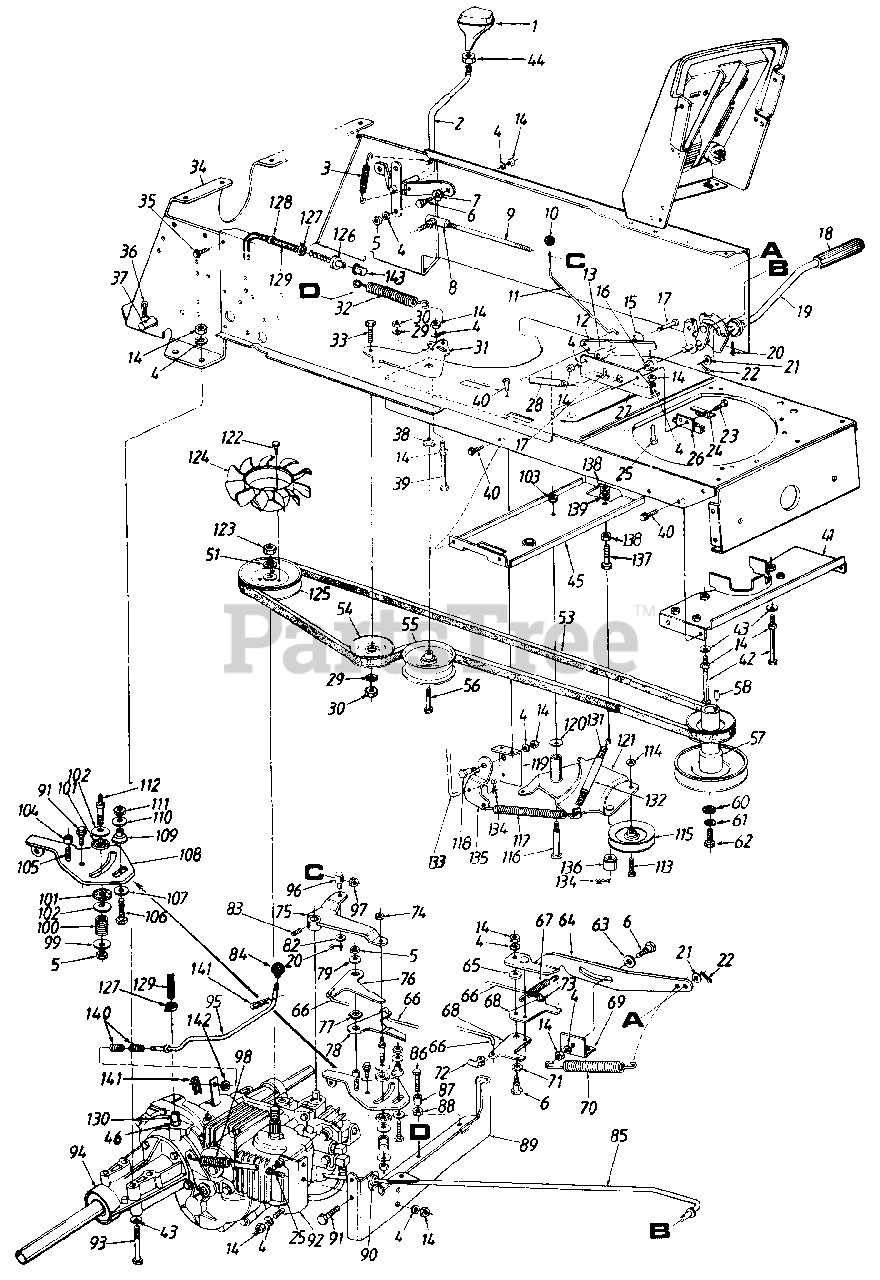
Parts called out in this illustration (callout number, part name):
1	Shift Knob
2	Speed Control Lever Ass'y.
3	Ext. Spring 2.75" Lg.
4	L-Wash. 5/16" I.D.
5	Hex Nut 5/16-24 Thd.
6	Shld. Bolt .437" Dia. x .268"
7	Spr. Wash. .445" I.D. x .75" O.D.
8	Ball Joint 5/16-24 Thd.
9	Speed Selector Adjusting Rod
10	Ball Knob
11	Brake Lockout Rod
14	Hex Nut 5/16-18 Thd.
15	Shld. Spacer .27" Lg.
16	Hex Flange Bearing
17	Hex Bolt 5/16-18 x 1.25" Lg.
18	Foot Pad
21	Fl-Wash. .34" I.D. x .68" O.D.
22	Cotter Pin 1/8" Dia. x 1" Lg.
23	Hex B-Tap Scr. #10 x .62" Lg.
24	Switch Plate
25	Hex Bolt 5/16-18 x .75" Lg.
26	Safety Switch (Clutch)
27	Clutch Ass'y. Mtg. Brkt.
28	Ext. Spring 2.51" Lg.
29	L-Wash. 3/8" I.D.
30	Hex Nut 3/8-16 Thd.
31	Idler Brkt.
32	Ext. Spring 4.75" Lg.
33	Hex Bolt 3/8-16 x 1.5" Lg.
36	Hitch Pin
37	Hitch Rod
38	Shld. Spacer .625" I.D.
39	Hex Bolt 5/16-18 x 2.75" Lg.
40	Hex Wash. Hd. TT-Tap Scr. 1/4-20 x .5" Lg.
43	Bell-Wash. .345" I.D. x .88" O.D.
44	Hex Jam Nut 3/8-16 Thd. (Gr. 5)
46	O-Ring
53	"V"-Belt
54	Idler Pulley
55	Fl-Idler Pulley
56	Hex Bolt 3/8-16 x 2" Lg. (Gr. 8)
57	Engine Pulley
58	Sq.-Key 1/4" x 1.5" Lg.
60	Fl-Wash. .44" I.D. x 1.25"
61	L-Wash. 7/16" I.D.
62	Hex Cap Bolt 7/16-20 x 1.5" Lg.
63	Fl-Wash. .531" I.D. x 1.25" O.D.
64	Neutral Return Link Ass'y.
65	Fl-Wash. .344" I.D. x 1.12" O.D. (Hdn).
66	Connecting Rod
67	Ext. Spring 2.5" Lg.
68	Balancer Brkt.
69	Bracket
70	Ext. Spring 3.94" Lg.
71	Spr.-Wash. .445" I.D. x .75" O.D.
72	Rod End Clevis Clip - R.H.
73	Rod End Clevis Clip - L.H.
74	Hex Ins. L-Nut 3/8-24 Thd.
75	Pintle Bracket Ass'y.
76	Flat Scissors
77	Spr. Wash. .625" I.D. x .885" O.D.
78	Offset Scissors
79	Fl-Wash. .344" I.D. x 1" O.D. (Hdn.)
82	Fl-Wash. .406" I.D. x .75" O.D.
83	Hex Socket Set Screw
84	Ball Knob
85	Brake Rod
86	Hex Wash. Hd. Scr. 1/4-20 x 1.5"
87	Spacer .39" Lg.
88	Hex Nut 1/4-20 Thd. (Gr. 5)
91	Hex Wash. Hd. TT-Tap Scr. 5/16-18 x . 62" Lg.
94	Transaxle (See Breakdown)
95	Bypass Rod
96	Ferrule 3/8-24 Thd.
97	Hex Jam Nut 3/8-24 Thd.
98	Ext. Spring 4.01" Lg.
99	Fl-Wash. .312" I.D. x .75" O.D.
100	Comp. Spring 1.19" Lg.
101	Friction Washer
102	Bell-Wash. .40" I.D. x 1.13" O.D.
103	Hex Cent. L-Nut 3/8-16 Thd.
104	Spacer
105	Rib Neck Bolt 5/16-18 x .62" Lg.
106	Hex Bolt 1/4-28 x 1" Lg. (Gr. 5)
107	Fl-Wash. .26" I.D. x .72" O.D.
108	Scissors Mtg. Brkt.
109	Centering Gauge Spacer
110	Bell-Wash. 1/4" I.D.
111	Hex Nut 1/4-28 Thd.
112	Friction Disc Stud
113	Hex Bolt 3/8-24 x 1.5" Lg.
114	Hex Cent. L-Nut 3/8-24 Thd.
115	V-Belt Idler
116	Shld. Bolt .498" Dia. x 2.05
117	Ext. Spring 6.12" Lg.
118	Shld. Bolt .437" Dia. x . 162"
119	Parking Brake Mtg. Brkt.
120	Bell-Wash. .38" I.D. x .88" O.D.
121	Idler Brkt. Deck Ass'y.
122	Hex Wash. Hd. Tap Scr. #12 x 3/8" Lg.
123	Hex Jam Nut 9/16-18 Thd.
124	Fan
125	Input Pulley
126	Plastic Vent
127	Hose Clamp
128	Cable Tie
129	Hose 1/2" I.D. x 18" Lg.
130	Hose Fitting
131	Ext. Spring 6.37" Lg.
132	Convoluted Conduit
133	Deck Control Rod
134	Internal Cotter Pin
135	Deck Control Pivot Brkt.
136	Spacer
137	Hex Bolt 1/4-20 x 2" Lg.
138	Hex Nut 1/4-20 Thd.
139	L-Wash. 1/4" I.D.
140	Compl Spring 1" Lg.
141	Hairpin Clip
142	Fl-Wash. 1/4" I.D.
143	Plastic Vent Cap
